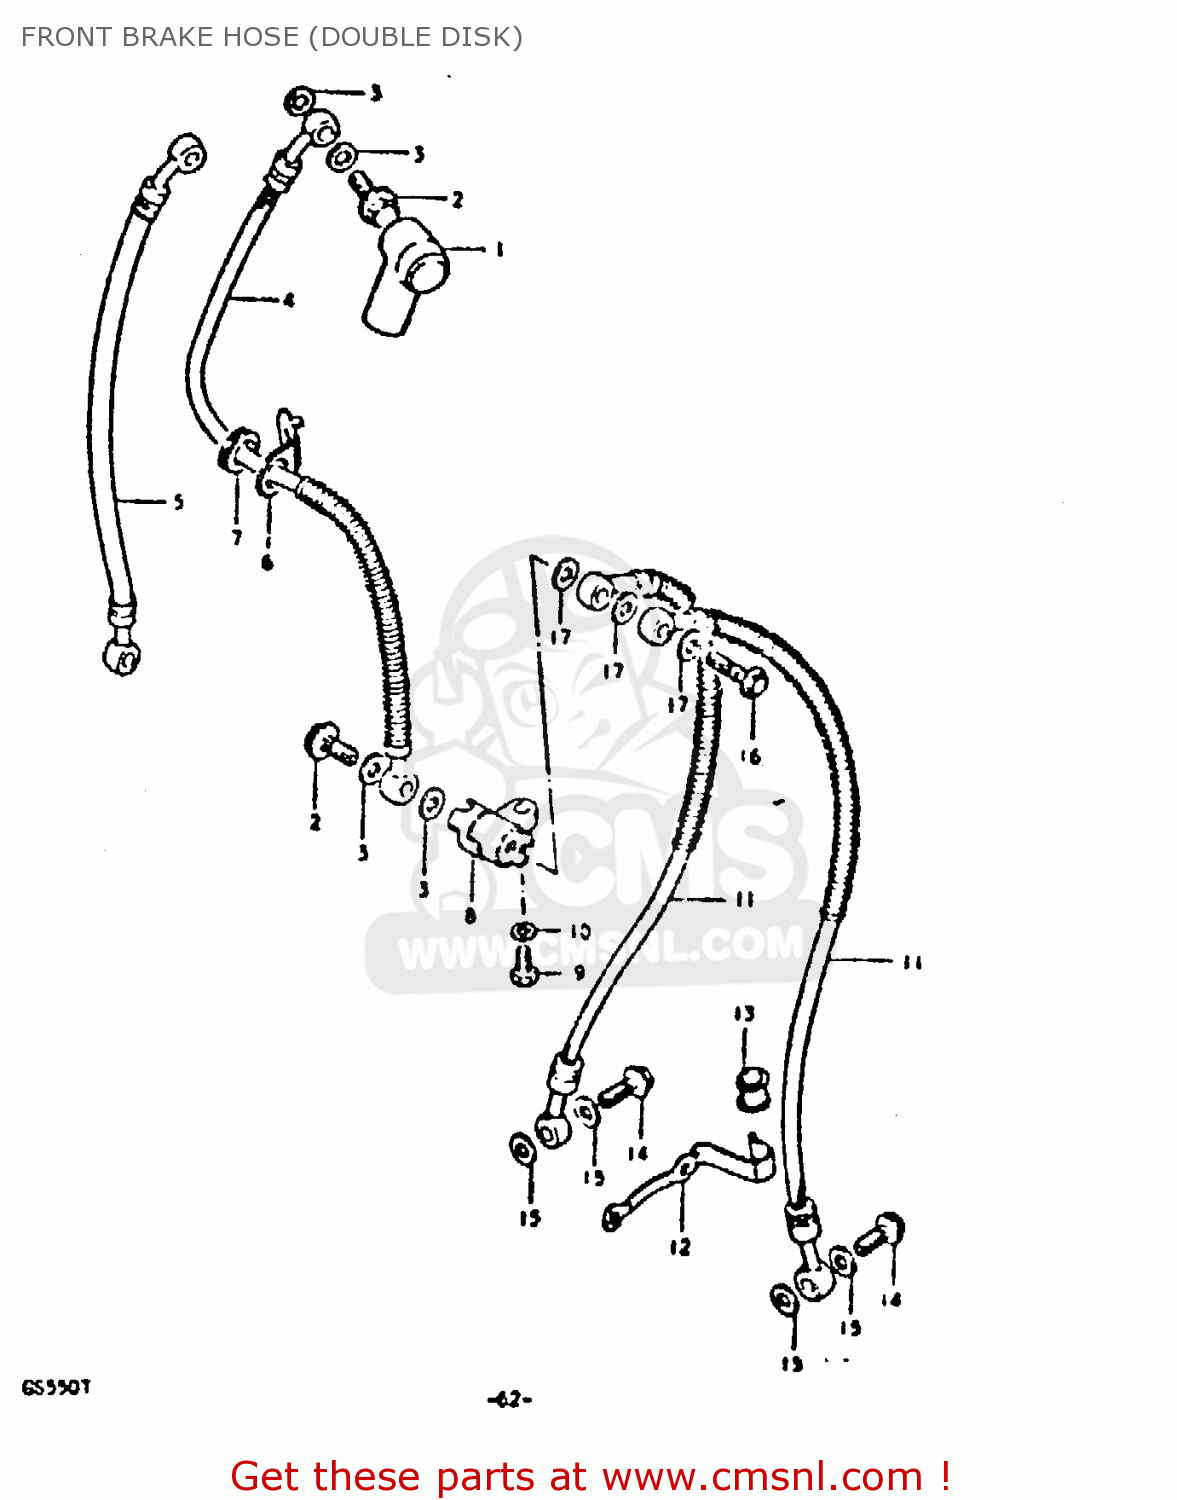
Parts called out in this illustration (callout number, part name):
1	BOOT,MASTER CYLINDER
2	BOLT,UNION
3	WASHER
4	HOSE,BRAKE NO.1
5	HOSE,FRONT BRAKE
6	GUIDE,BRAKE HOSE
7	GROMMET
8	JOINT,BRAKE HOSE
9	BOLT
10	LOCK WASHER
11	HOSE,BRAKE NO.2
12	GUIDE,BRAKE HOSE NO.2
13	BUSH,BRAKE HOSE GUIDE,NO.2
14	BOLT,UNION
15	WASHER
16	BOLT,UNION
17	WASHER
